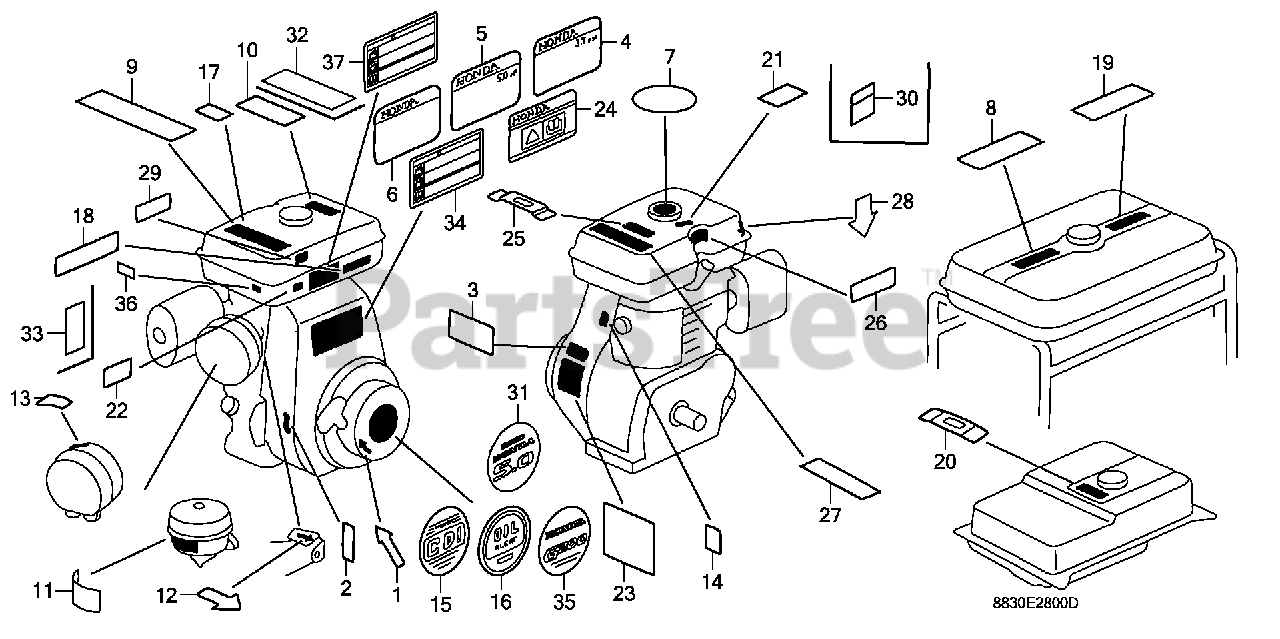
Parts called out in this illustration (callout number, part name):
5	EMBLEM Use up to Engine SN 1208881.
9	MARK, CAUTION (ENGLISH/FRENCH/SPANISH)
12	MARK, CHOKE Use up to Engine SN 1208717.
12	MARK, CHOKE
19	MARK A, CAUTION
19	MARK, CAUTION
23	MARK, OIL CAUTION
